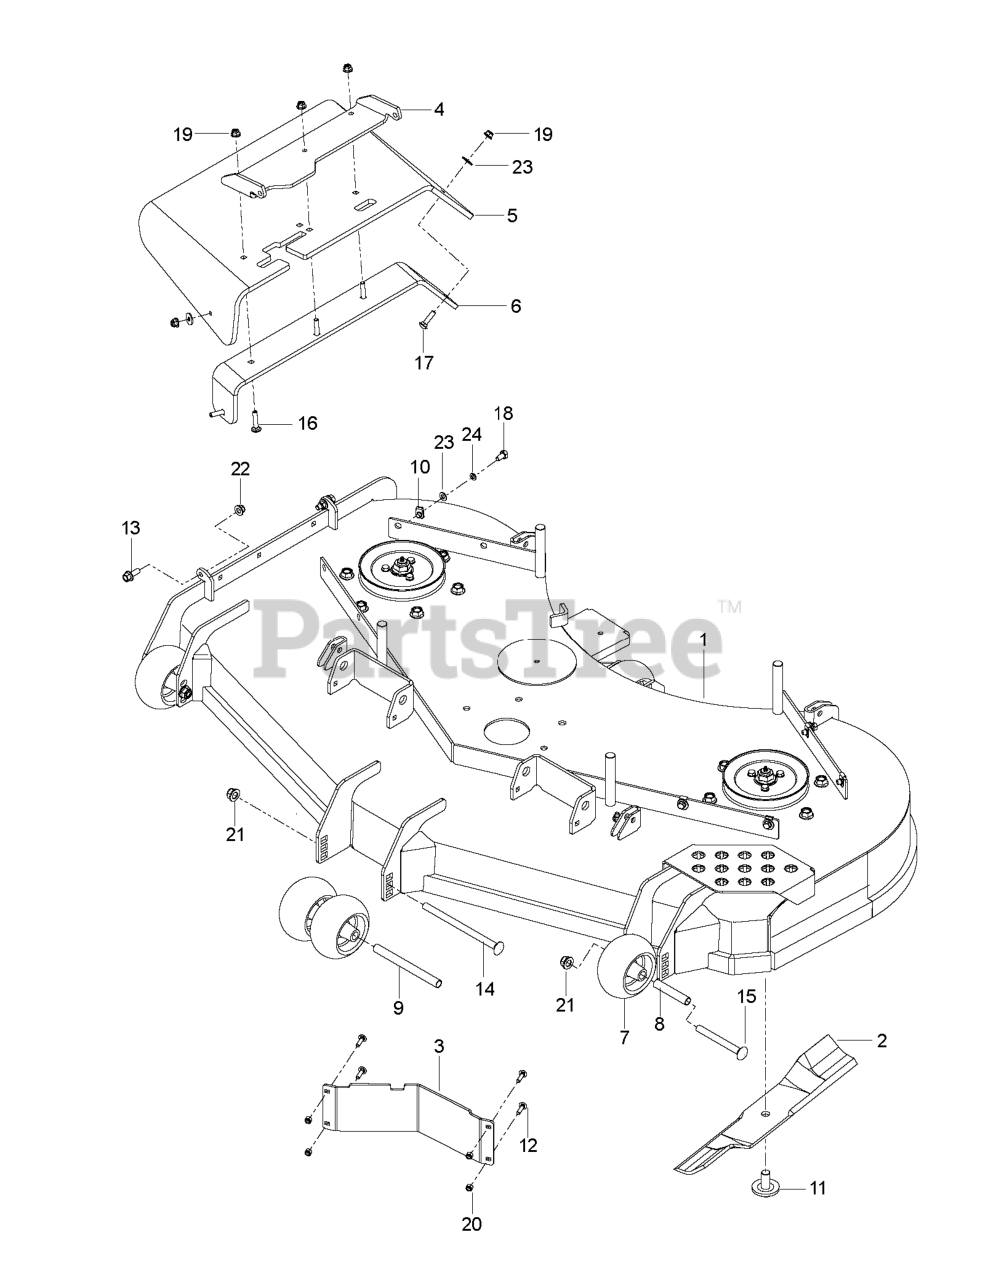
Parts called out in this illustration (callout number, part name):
1	DECK.SVC.W/DECALS.PZ.60"
2	BLADE - HEAVY DUTY 21"
3	BAFFLE, DIVERTER 54"/60" LH
4	BRKT - CHUTE MTG BLACK
5	CHUTE, DISCHARGE 48-52
6	BRKT, CHUTE SUPPORT BLACK
7	ROLLER, GAUGE .635 BORN
8	TUBE, ROLLER AXLE
9	TUBE, ROLLER AXLE LONG
10	U-CLIP 5/16-18 NUT RETAINER
11	BLADE BOLT/WASHER
12	1/4-20X3/4 CARR BLT
13	HHFS 3/8-16 X 1 GRD 5 ZD
14	RHSNB 1/2-13 X 8 GR5 ZD
15	RHSNB 1/2-13 X 4.75 GR5 ZD
16	RHSNB 5/16-18 X 1-1/2 GR 5 ZD
17	BOLT, CARRIAGE 5/16X1-1/4
18	BOLT.FIN.HEX.5/16-18UNC X 1.00
19	5/16-18 NYLOC FLANGE NUT
20	NUT.1/4-20.HEX.NYLOC.ZD
21	NUT, 1/2-13 HEX FLG NYLOC ZD
22	NUT 3/8-16 HEX FLG NYLOC ZD
23	WASHER.5/16.FLAT.STE.STD.
24	WASH.5/16.SLW.ZD
